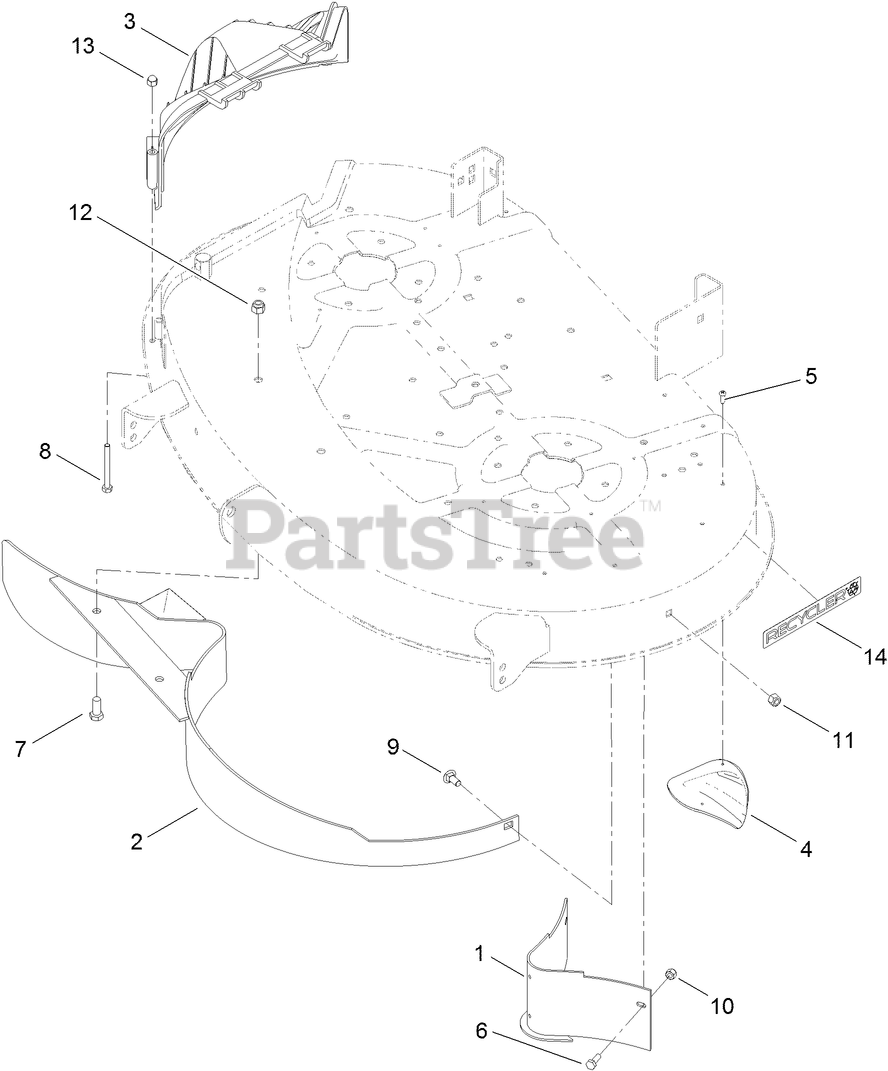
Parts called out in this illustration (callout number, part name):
1	BAFFLE ASM
2	BAFFLE ASM
3	COVER-RECYCLER
4	PLATE-KICKER
5	SCREW-PPH
6	SCREW-HH
7	SCREW-HH
8	SCREW-HH
9	BOLT-CARR
10	NUT-LOCK, NI
11	NUT-LOCK, NI
12	NUT-LOCK, NI
13	NUT-CAP
14	DECAL-RECYCLER
